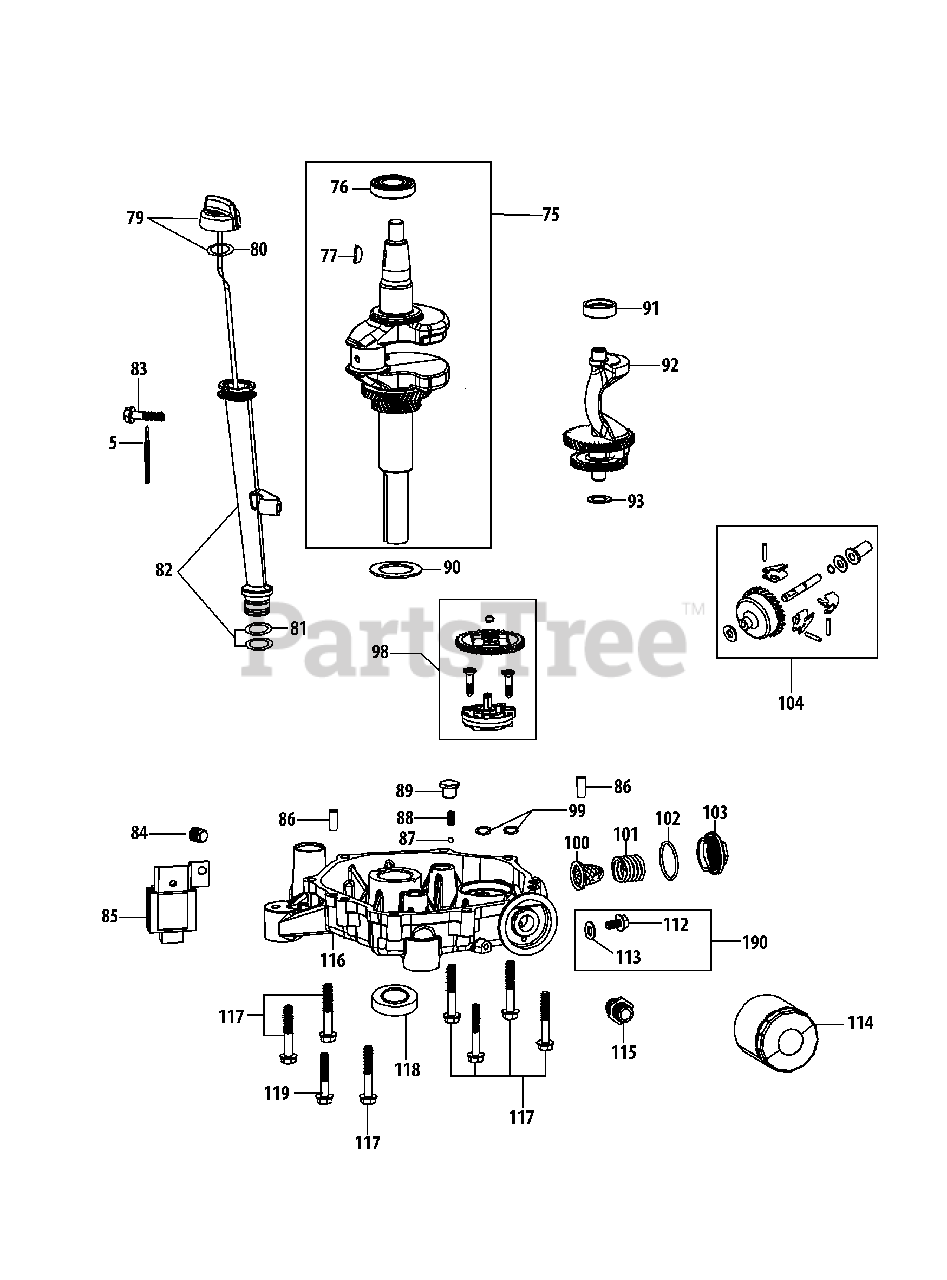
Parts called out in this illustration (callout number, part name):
5	Flexible Clamp
75	Crankshaft Assembly
76	Main Bearing
77	Woodruff Key
79	Dipstick Assembly
80	Upper O-Ring
81	Lower O-Ring
82	Oil Fill Tube Assembly
83	Bolt M6×35
84	Oil Drain Plug
85	Regulator
86	Dowel Pin 8×14
87	Ball 6.35
88	Spring
90	Crankshaft Thrust Washer
91	Balanceable Shaft Bearing
92	Balanceable Shaft Assembly
93	Balanceable Thrust Washer
98	Oil Pump Assembly
99	O-Ring 10×2.65
100	Filter
101	Filter Spring
102	O-Ring 35.5×2.65
103	Filter Cover
104	Governor Gear/Shaft Assembly
112	Bolt M8×15
113	Oil Drain Plug Washer
114	Oil Filter
115	Screw Joint
116	Crankcase Cover
116	Crankcase Cover Assembly
117	Bolt M8×54
118	Lower Crankshaft Seal
119	Bolt M8×43
190	Oil Drain Plug Assembly
